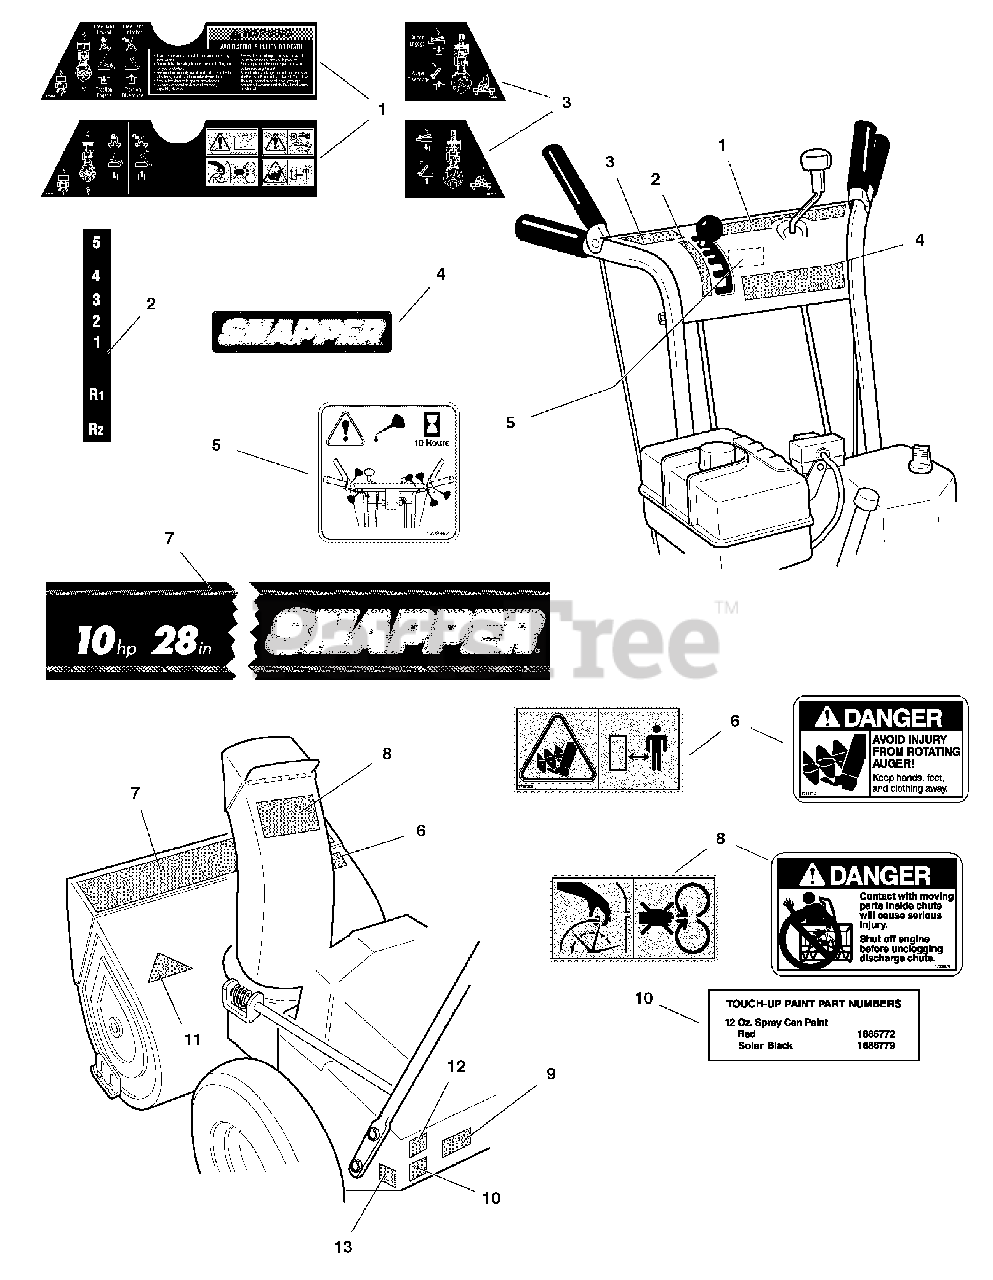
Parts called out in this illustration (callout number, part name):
1	DECAL, Dashboard
2	DECAL, Shift Pattern
3	DECAL, Auger Control
4	DECAL, Snapper, Front Dash, 1-3/4 x 7-1/2
5	DECAL, Handle Lubrication
6	DECAL, Auger Impeller Warning
7	DECAL, Snapper, 9HP, 24" Stripe
7	DECAL, Snapper, 10HP 28" Stripe
7	DECAL, Snapper, 11HP 32" Stripe
7	DECAL, Snapper, 12HP 38" Stripe
8	DECAL, Discharge Chute, Danger
9	DECAL, Patent
10	DECAL, Touch Up Paint Snapper/Massey Red
11	DECAL, OPEI Certified ANSI
12	LABEL, ID Plate
13	LABEL, Decibel
